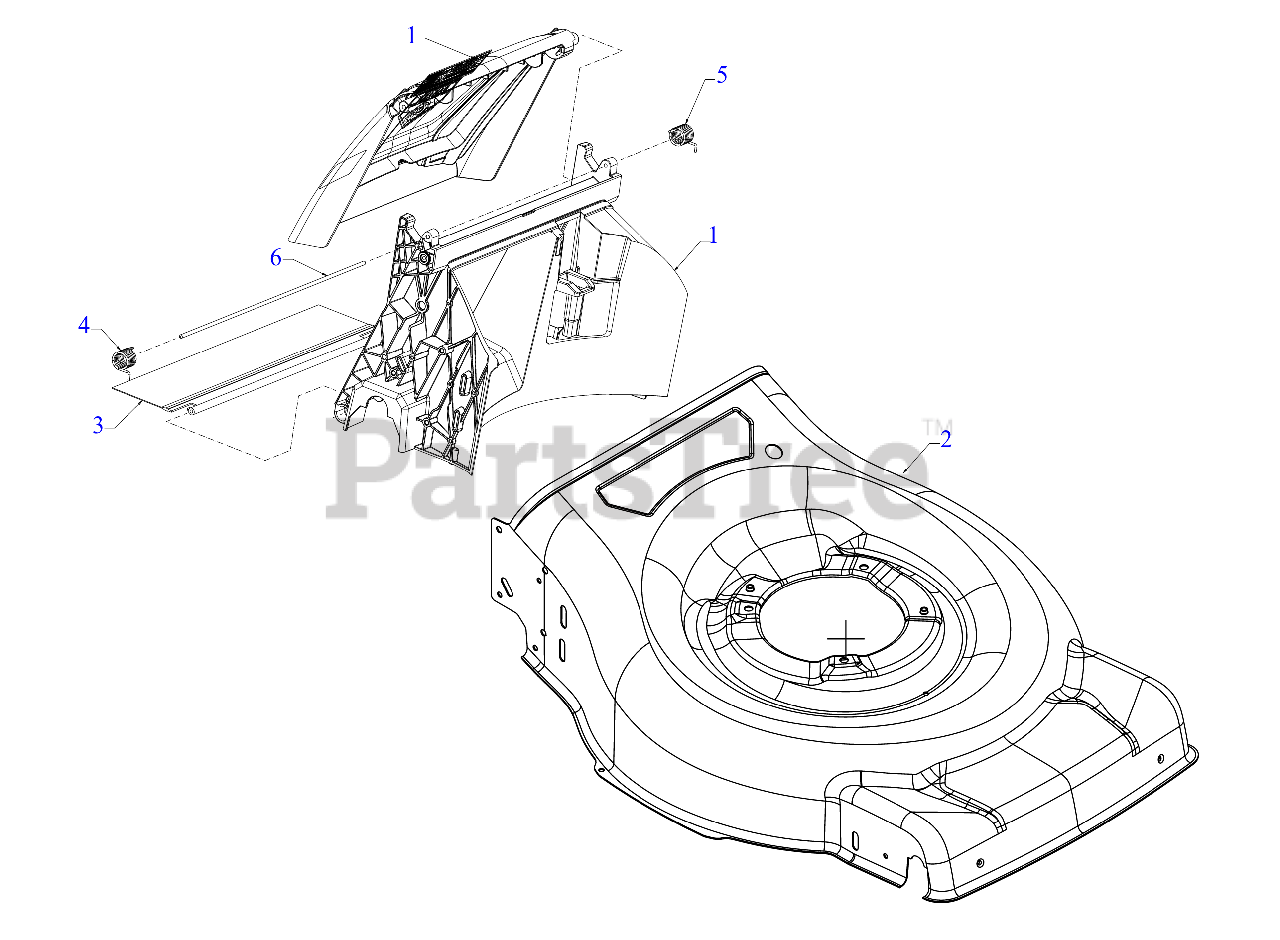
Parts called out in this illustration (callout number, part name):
1	23" BAG BAFFLE (REAR)
2	23" RWD DECK
3	TRAILSHIELD (4.54 x 18)
4	TORSION SPRING (RH)
5	TORSION SPRING (LH)
